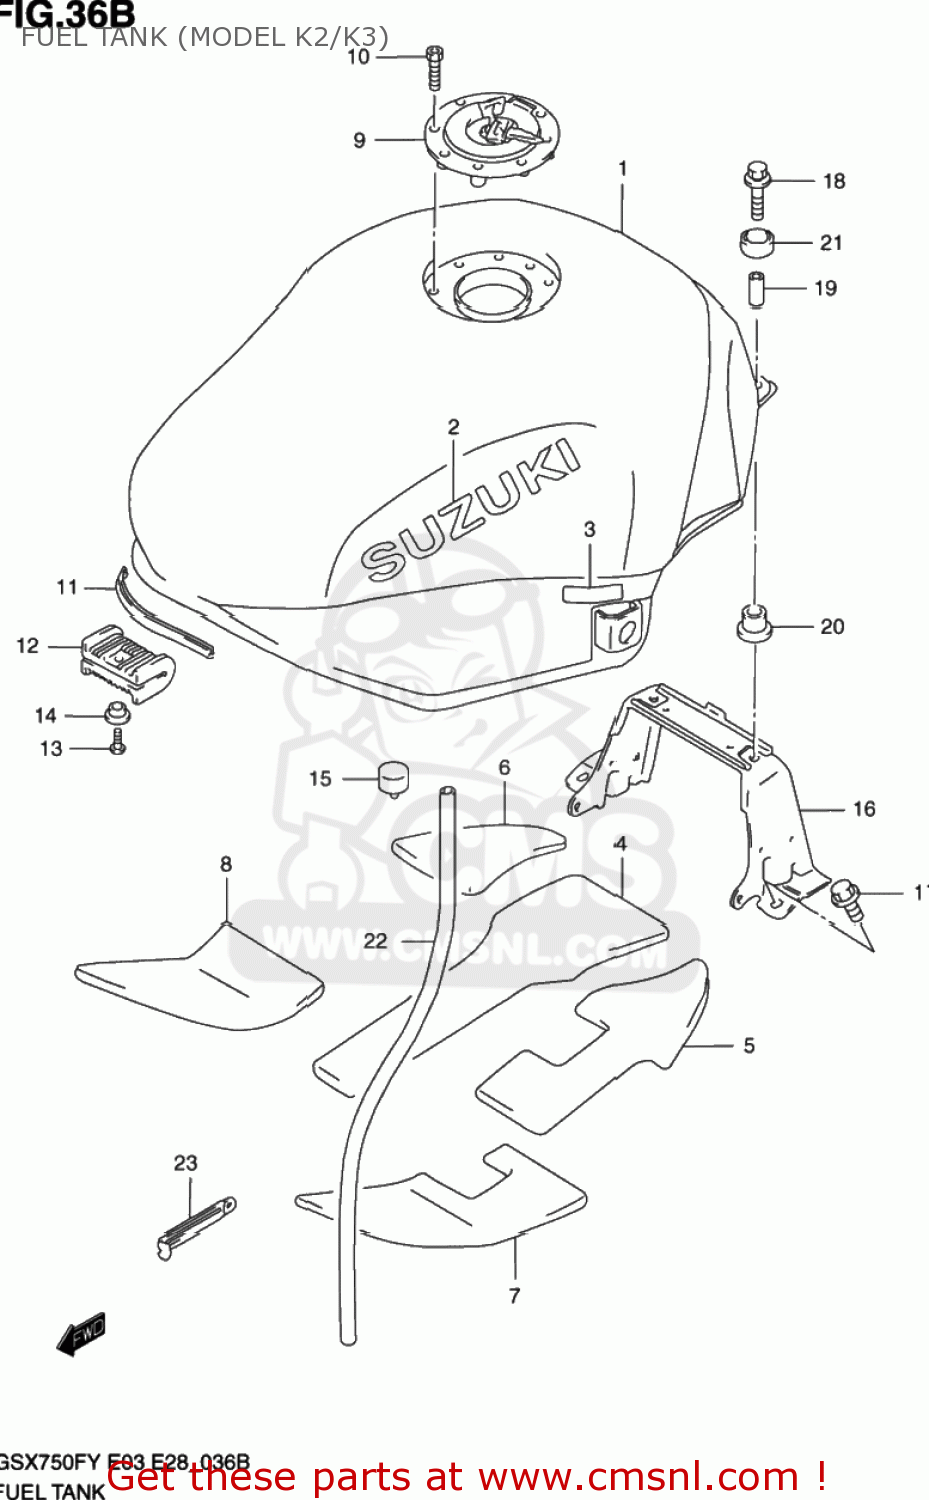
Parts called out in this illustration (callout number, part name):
1	TANK ASSY,FUEL(BLACK)
2	EMBLEM
3	PROTECTOR(12X40)
4	SHIELD,FUEL TANK HEAT NO.1
5	SHIELD,FUEL TANK HEAT NO.2
6	SHIELD,FUEL TANK HEAT NO.3
7	SHIELD,FUEL TANK HEAT NO.4
8	SHIELD,FUEL TANK HEAT NO.5
9	CAP SET,FUEL TANK
10	BOLT(5X20)
11	MOLDING,FUEL TANK
12	CUSHION,FUEL TANK FR
13	SCREW 5X12
14	WASHER
15	CUSHION
16	BRACKET,FUEL TANK RR
17	BOLT
18	BOLT(6X30)
19	SPACER(6.5X9X18)
20	CUSHION
21	CUSHION
22	HOSE,FUEL TANK WATER DRAIN
23	CLAMP(L:120 T:1.0)
